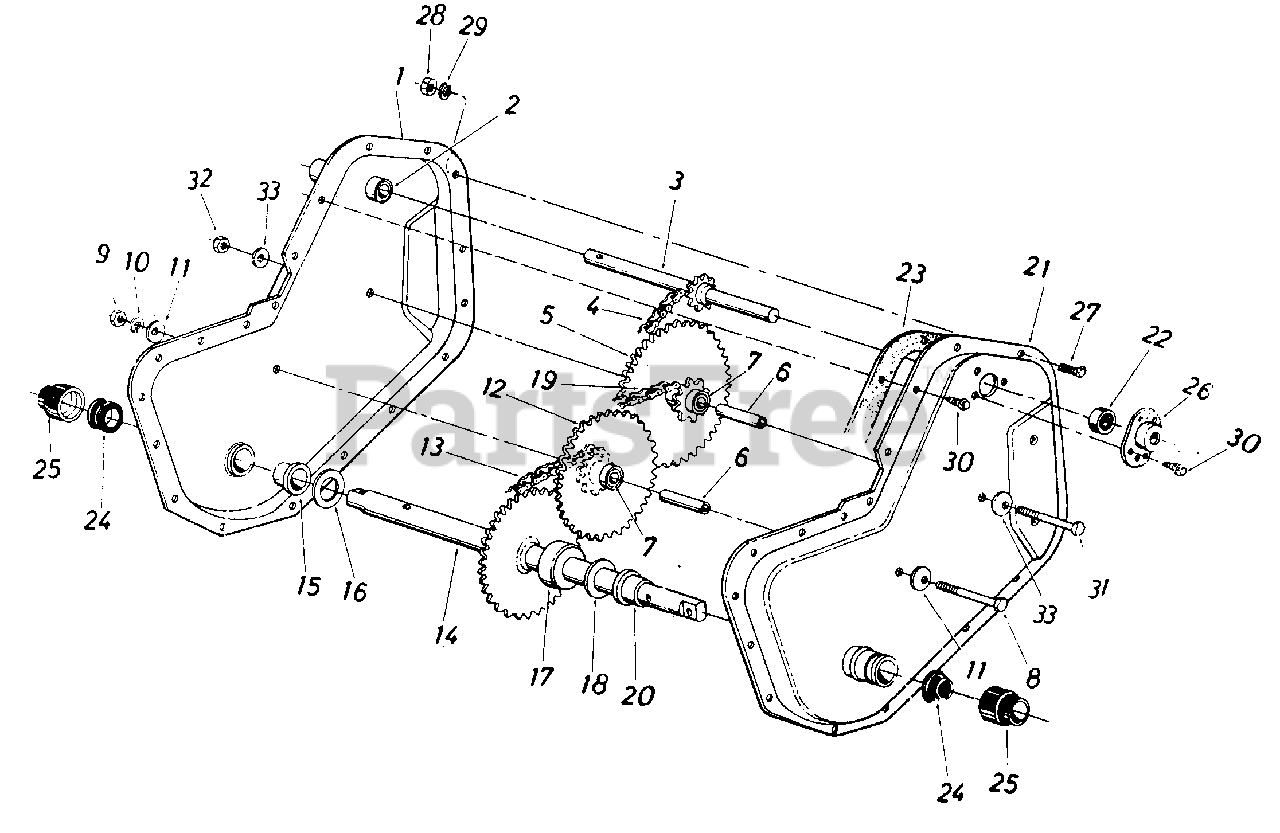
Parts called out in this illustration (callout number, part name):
1	HOUSING-CHAIN CASE
3	SHAFT ASSY-INPUT
4	#35 CHAIN 3/8 PITCH X 44 LINKS E
5	SPROCKET & HUB ASSY-9T & 36T
6	BEARING-INNER RACE
7	BEARING-SLEEVE
8	SCREW-HEX 3/8-24 X 2.50
9	NUT-HEX INS L-3/8-24
10	WASHER-LOCK-3/8
11	WASHER-BELL .3/8ID X 1.12OD X .030
12	SPROCKET & HUB ASSY-9T & 22T
13	#420 CHAIN 1/2 PITCH X 28 LINKS E
14	SHAFT ASSY-WHEEL
15	BEARING-FLANGE
16	WASHER-FL-.88 X 1.50 X .030
17	SPACER
18	WASHER-FL-.88 X 1.50 X .030
19	#420 CHAIN 1/2 PITCH X 30 LINKS E
20	BEARING-FLANGE
23	GASKET
26	HOUSING-BRG
27	SCREW-HEX 1/4-28 X .62
28	NUT-HEX 1/4-28
29	LOCK WASHER 1/4 DIA
30	SCREW-HEX WASH SF TAPP
31	SCREW-HEX
32	NUT-HEX CENTER L-5/16-18
33	WASHER-FL-.344 ID X .88 OD X .063
